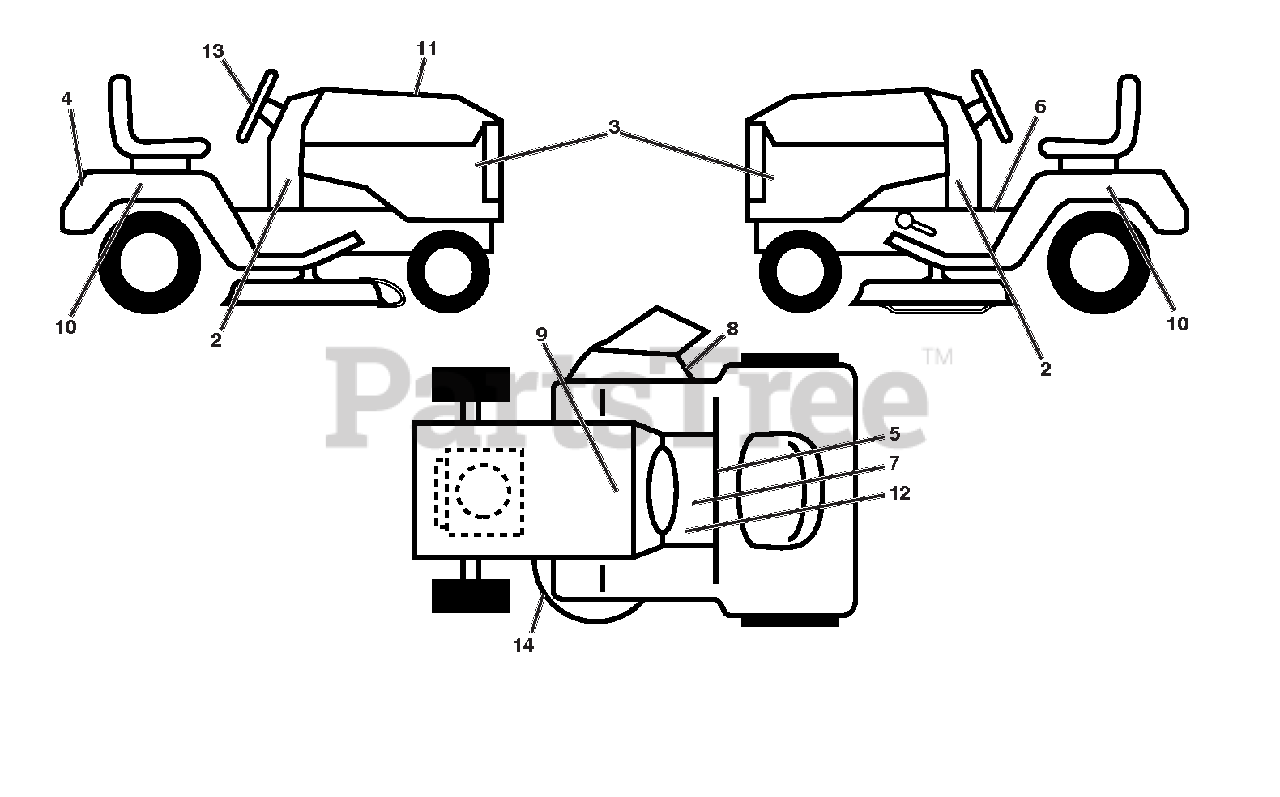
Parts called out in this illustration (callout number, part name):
2	DECAL.DASH
3	DECAL.SDPNL.PWRDBY KOHL.ARIENS
4	Decal, Fender
5	DECAL.FENDER
6	DECAL, WARNING START INST.
7	Decal, Spark Arrester
8	DECAL.MOWER.WARN.KEEP HAND AWY
9	DECAL.BAT.DAN/POI P/L SYM.WPN
10	DECAL.FENDER.SIDE.HYDRO.ARIENS
11	PARTS MANUAL
12	LABEL EMISS
13	DECAL.WHEEL.STEER.ARIENS
14	DECAL.V-BELT.SCH.42/46"MEC/ELE
